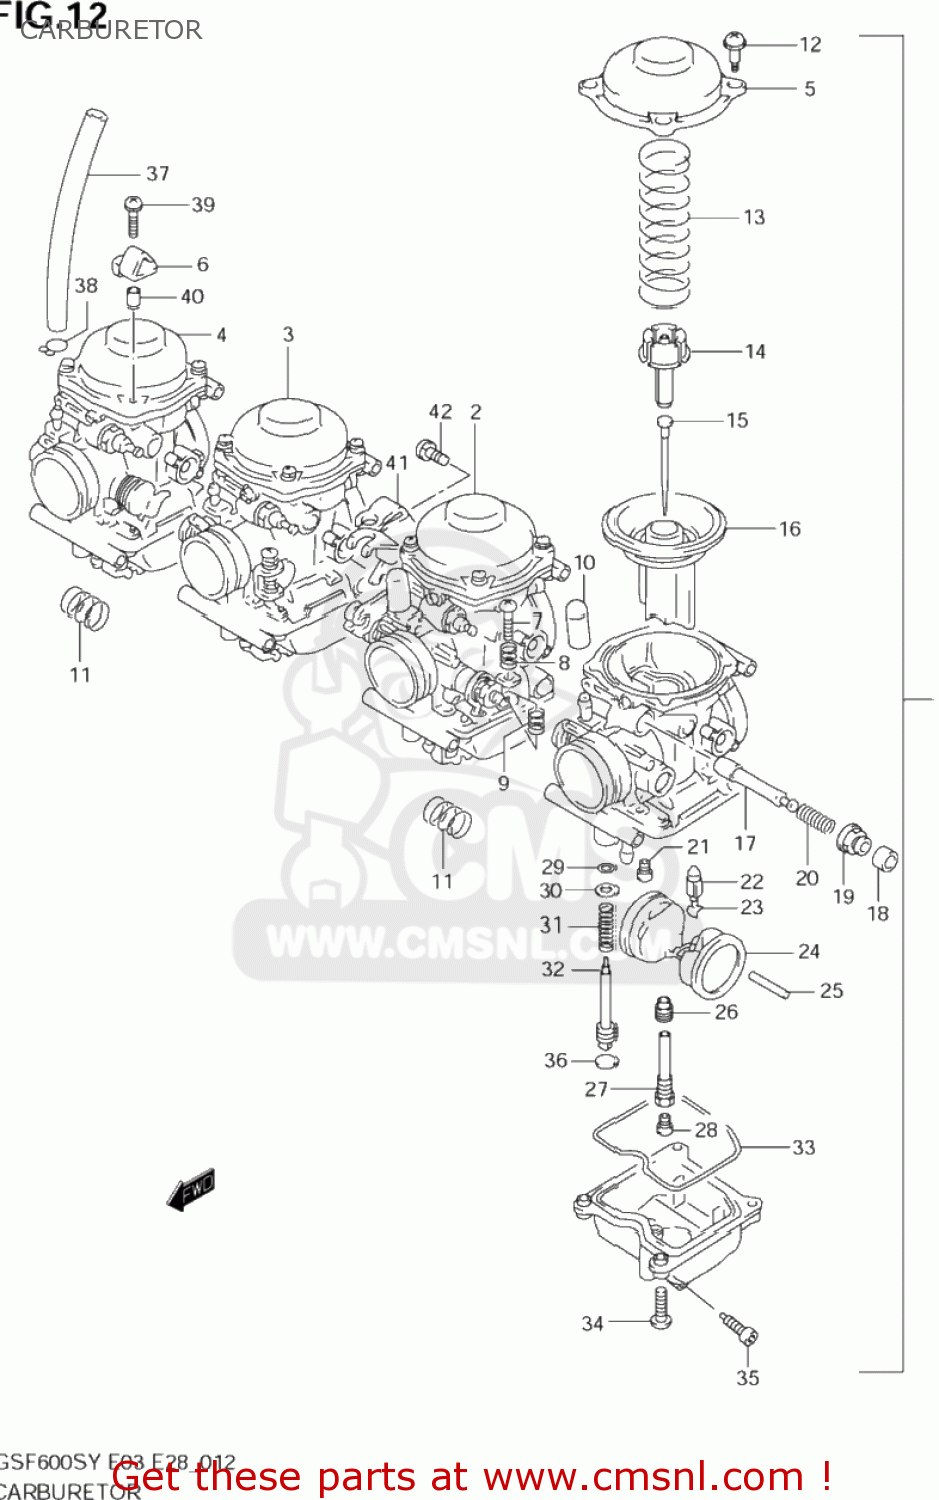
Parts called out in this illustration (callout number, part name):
1	CARBURETOR ASSY,L
2	CARBURETOR ASSY,ML
3	CARBURETOR ASSY,MR
4	CARBURETOR ASSY,R
5	TOP
6	STAY,PLATE
7	SCREW
8	SPRING
9	SPRING
10	CAP
11	SPRING
12	SCREW
13	SPRING
14	SEAT,SPRING
15	NEEDLE,JET(N1QA)
16	VALVE PISTON
17	VALVE,STARTER
18	CAP
19	CAP
20	SPRING
21	JET,SLOW(35)
22	VALVE ASSY,NEEDLE
23	CLIP
24	FLOAT ASSY
25	PIN,FLOAT
26	JET,NEEDLE
27	HOLDER,NEEDLE JET
28	JET,MAIN(92)
29	O RING
30	WASHER
31	SPRING
32	SCREW,PILOT
33	O RING
34	SCREW
35	PLUG,DRAIN
36	CAP
37	HOSE(5X9X600)
38	CLIP
39	SCREW
40	COLLAR
41	PLATE
42	SCREW
